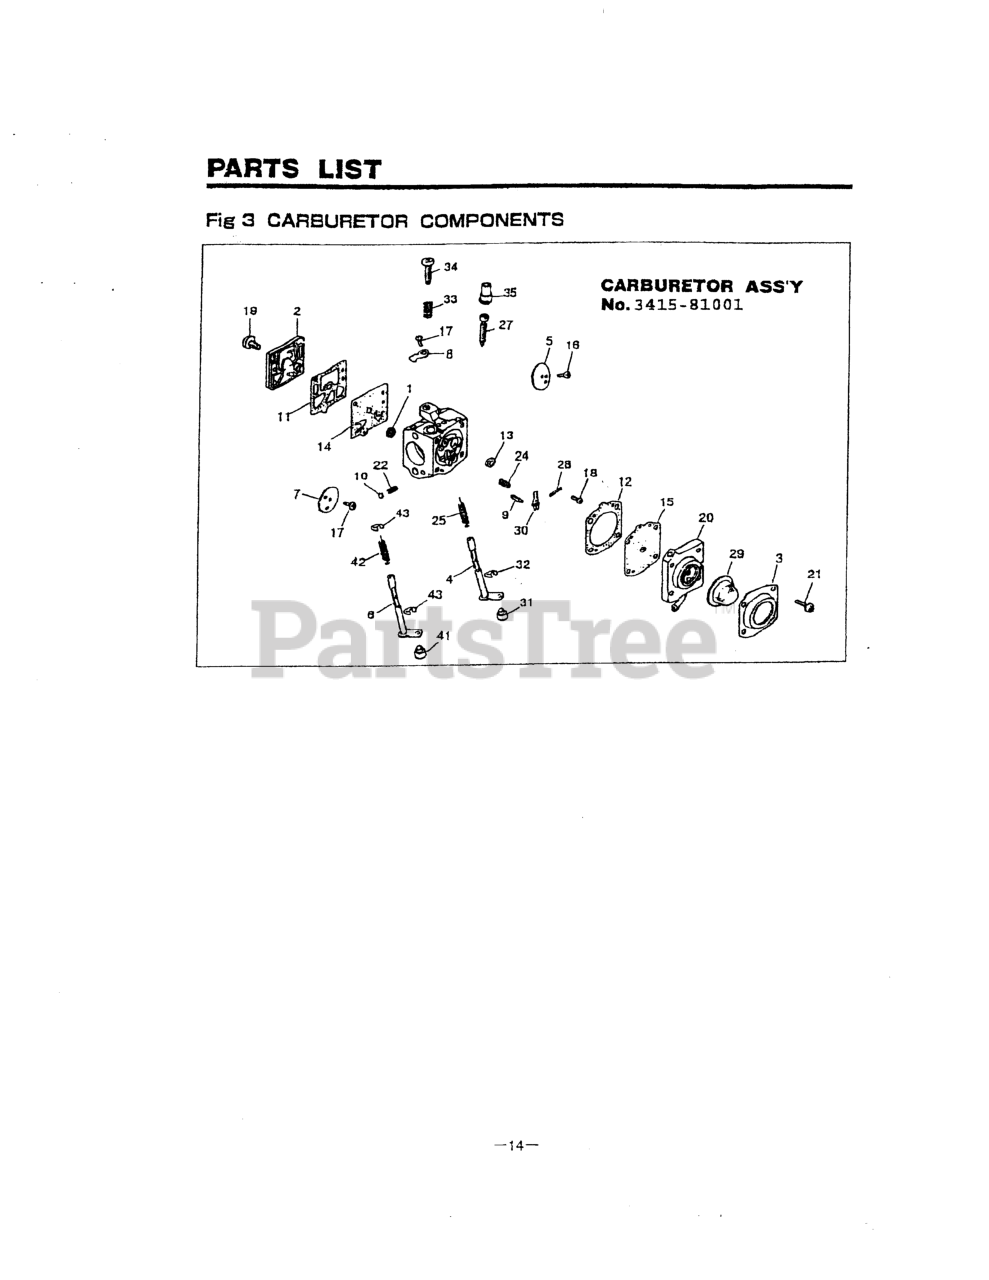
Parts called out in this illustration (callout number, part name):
2	COVER, PUMP
3	COVER, PUMP
4	SHAFT ASSEMBLY
6	SHAFT, CHOKE
7	VALVE, CHOKE
9	VALVE, INLET
10	BALL, FRICTION
11	KIT ONLY
12	KIT ONLY
13	PLUG, WELSH
14	KIT ONLY
19	SCREW (RPLS 1491-81130)
20	BODY ASSY (RPLS 1491-81490)
21	SCREW (REPLACES 1491-81350)
22	SPRING
25	SPRING
27	NEEDLE, H
28	PIN, METERING LEVER
29	PUMP, PRIMER
30	KIT ONLY
31	SWIVEL (USE -06040)
33	SPRING, IDLE
